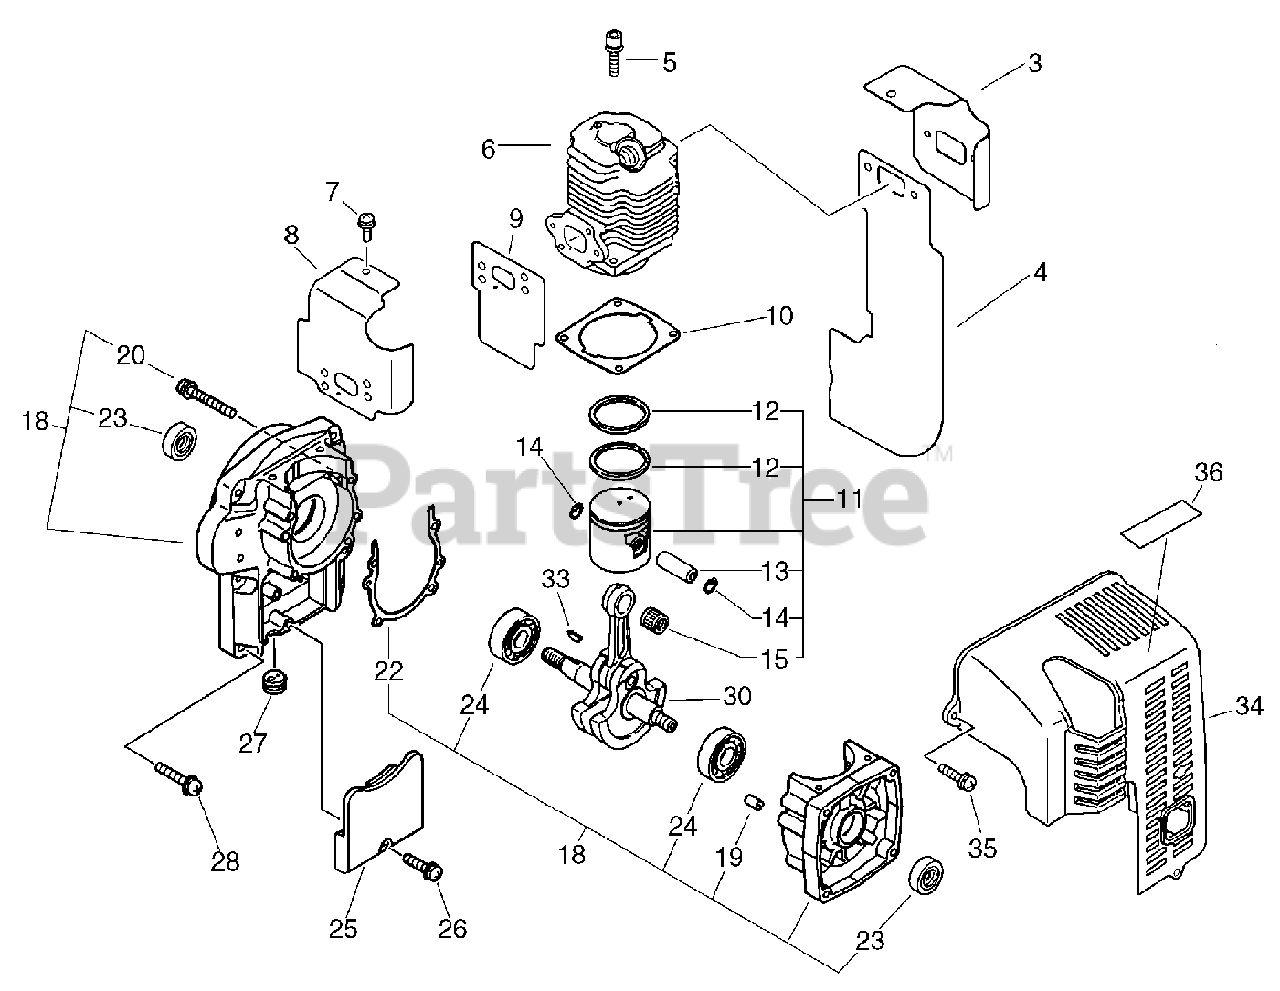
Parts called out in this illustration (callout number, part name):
3	COVER, CYLINDER - EXHAUST
4	SHIELD, EXHAUST
5	SCREW - 5X22
6	CYLINDER
7	SCREW - 5X10
8	SHIELD, CYLINDER - INTAKE
9	SHIELD, INTAKE
10	GASKET, CYLINDER
11	PISTON KIT
12	RING, PISTON
13	PIN, PISTON
14	RING, RETAINING - 8
15	BEARING, NEEDLE
18	CRANKCASE KIT
19	PIN - LOCATING
20	SCREW - 5X40
22	GASKET, CRANKCASE
23	SEAL, OIL
24	BEARING, BALL - 6202
25	COVER, DUST
26	SCREW - 5X18
28	SCREW - 5X25
30	CRANKSHAFT ASSY
33	KEY - 3X14
34	COVER, ENGINE
35	SCREW - 5X20
36	LABEL - HOT SURFACE
